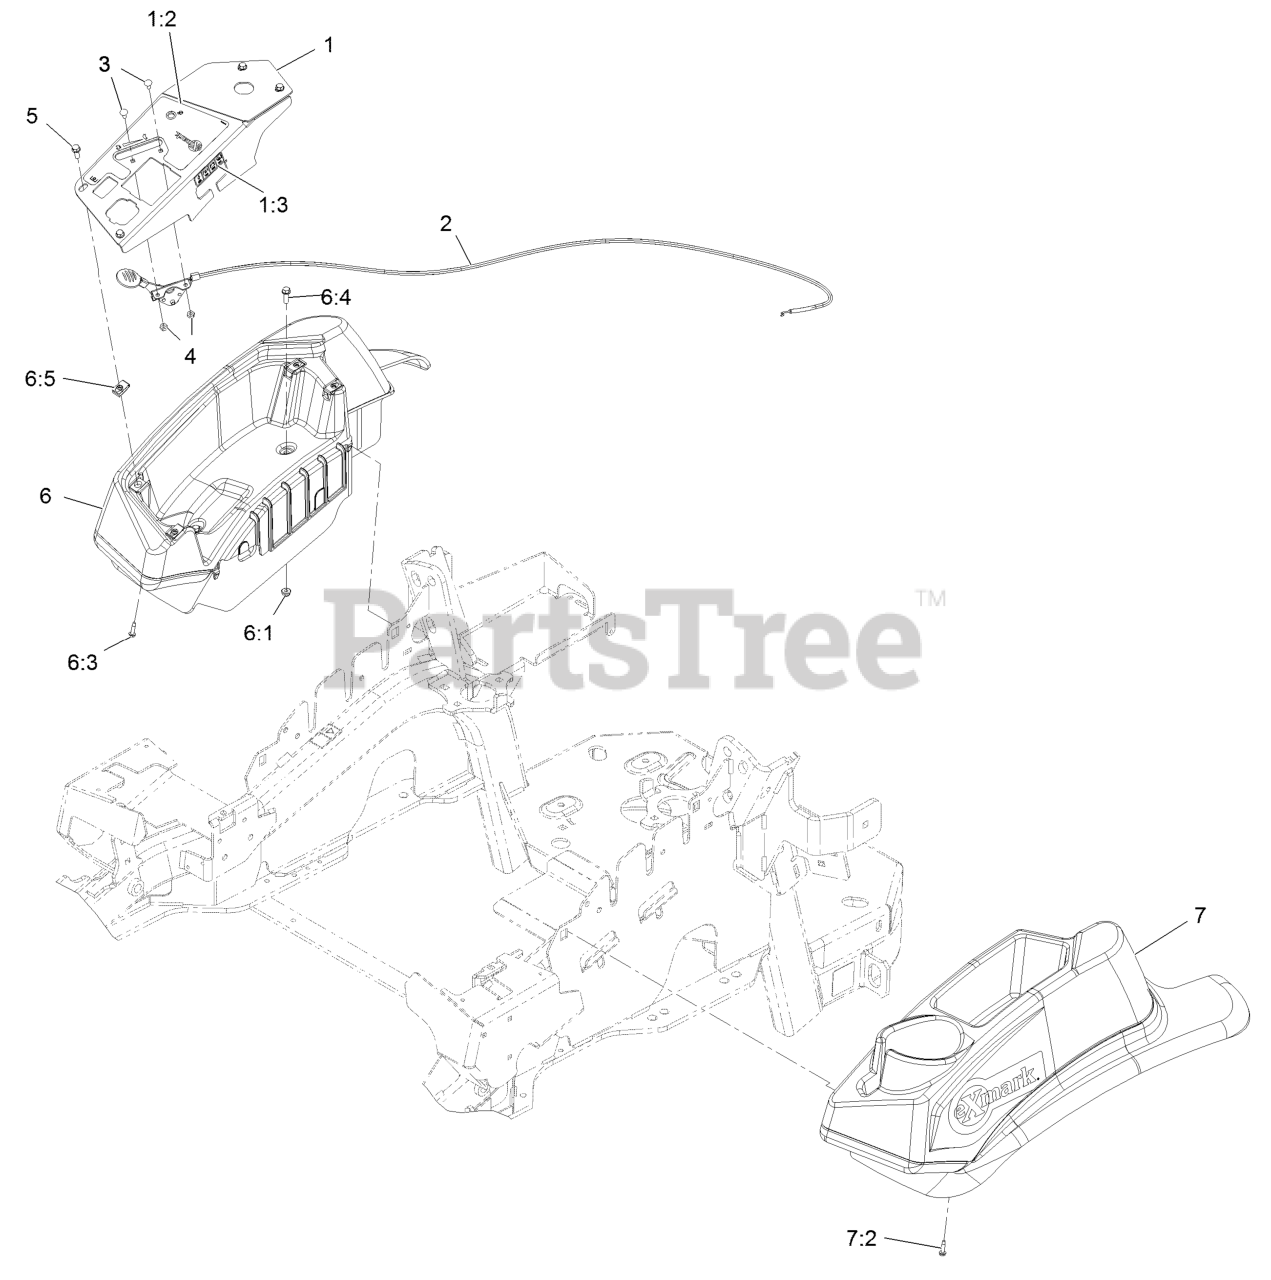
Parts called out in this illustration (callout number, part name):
1	ASM,CONTROL PANEL W/DECAL
1:2	DECAL-CONTROL PANEL EFI
1:3	DECAL-FUSES
2	ASM,THROTTLE CABLE
3	BOLT-CARR
4	NUT-LOCK, NI
5	SCREW-HWH
6	CONSOLE,RH NARROW ASM
6:3	SCREW,THD FORM,HWH
6:4	SCREW-HWH
6:5	Nut-Retainer-Panel 1/4-20
7	CONSOLE.LH NARROW ASM
7:2	SCREW,THD FORM,HWH
